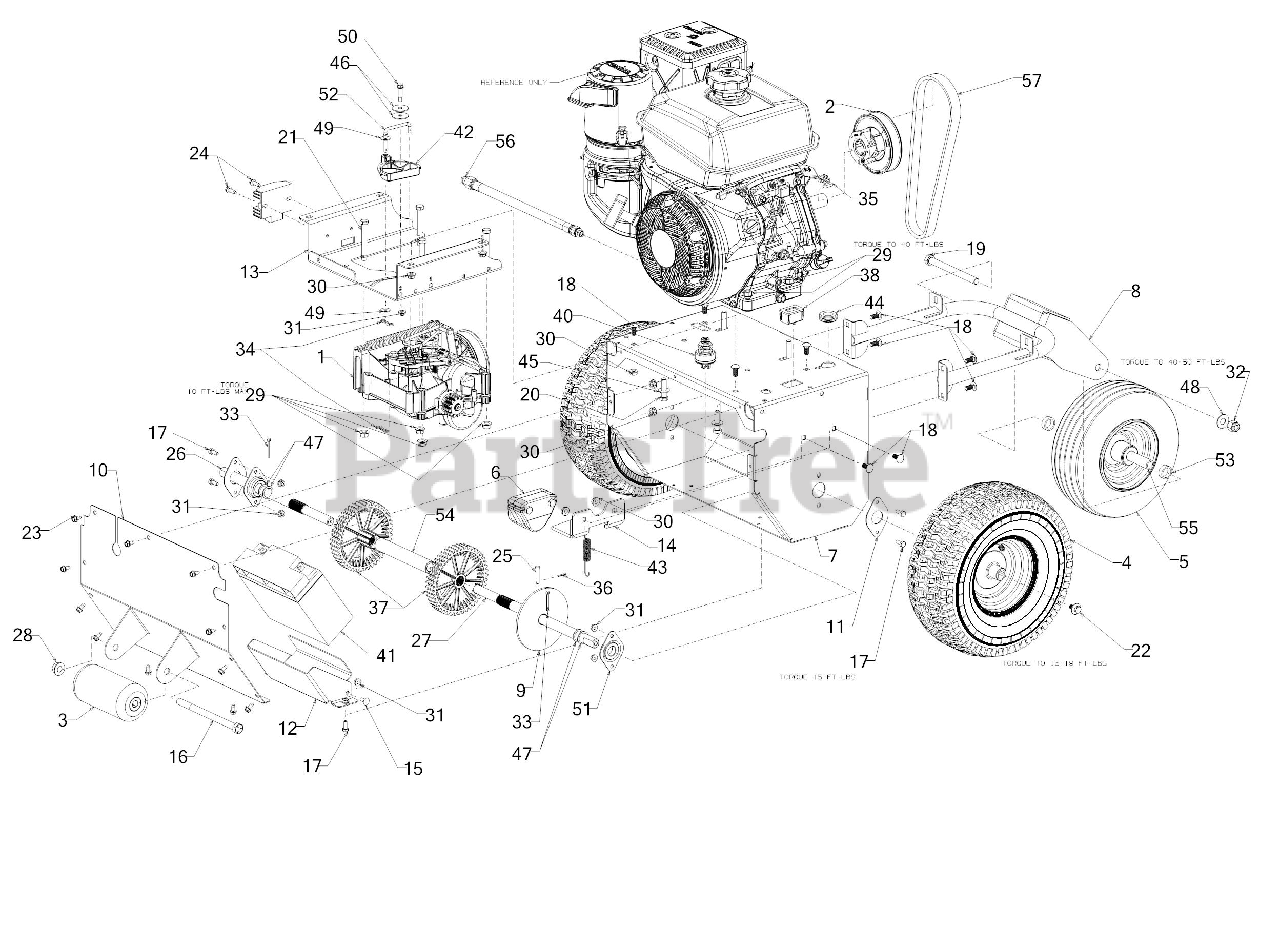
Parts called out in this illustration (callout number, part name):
1	TRANSMISSION ASSEMBLY BLOWER
2	PULLEY ASSEMBLY
3	ROLLER ASSEMBLY
4	TIRE 13 X 5 X 6 DELI
5	WHEEL ASSEMBLY 11 x 4 x 5
6	TRANSFER CASE BRAKE ASSEMBLY
7	TRANSMISSION HOUSING
8	FRONT WHEEL BRACKET ASSEMBLY
9	ROTOR HUB ASSEMBLY
10	FRONT COVER ASSEMBLY
11	RETAINING PLATE
12	BATTERY TRAY
13	TRANSMISSION MOUNTING PLATE BLOWER
14	CALIPER MOUNTING BRACKET BLOWER
15	CARRIAGE BOLT 1/4-20 x .62
16	SCREW 1/2-13 x 7 GR5
17	SCREW 1/4-20 x .62 SPEC GR5
18	CARRIAGE BOLT 5/16-18 x .75
19	SCREW 1/2-20 x 5.50 GR5
20	SCREW 3/8-16 x 1.50
21	SCREW 3/8-16 x 3 GR8
22	SCREW 5/16-24 x .750 GR5
23	SCREW 1/4-20 X.500
24	SCREW 1/4-20 x .750
25	CLEVIS PIN
26	13.10" AXLE (LH)
27	14.50" AXLE (RH)
29	HEX LOCK NUT
30	FLANGE NUT
31	LOCK NUT 1/4
32	HEX NUT CENTER
33	COTTER PIN-5/32 DIA
34	BOW TIE COTTER PIN 1/4-5/16
36	COTTER PIN-3/32X62
37	NYLON GEAR 45 TOOTH
40	KEY SWITCH (3 POSITION)
41	SEALED BATTERY 12 VOLT
42	CABLE GUIDE
43	EXTENSION SPRING
44	RUBBER GROMMET
45	FLAT WASHER
46	FLAT WASHER .322 ID x 1.25 x .060
47	FLAT WASHER .750X1.000X.060:HD
48	FLAT WASHER
49	FLAT WASHER
50	SHOULDER SCREW
51	BALL BEARING
52	SPEED CONTROL ROD LINK
53	SPACER .790 ID 1
54	AXLE SUPORT TUBE
55	WHEEL SPACER
56	OIL DRAIN HOSE
